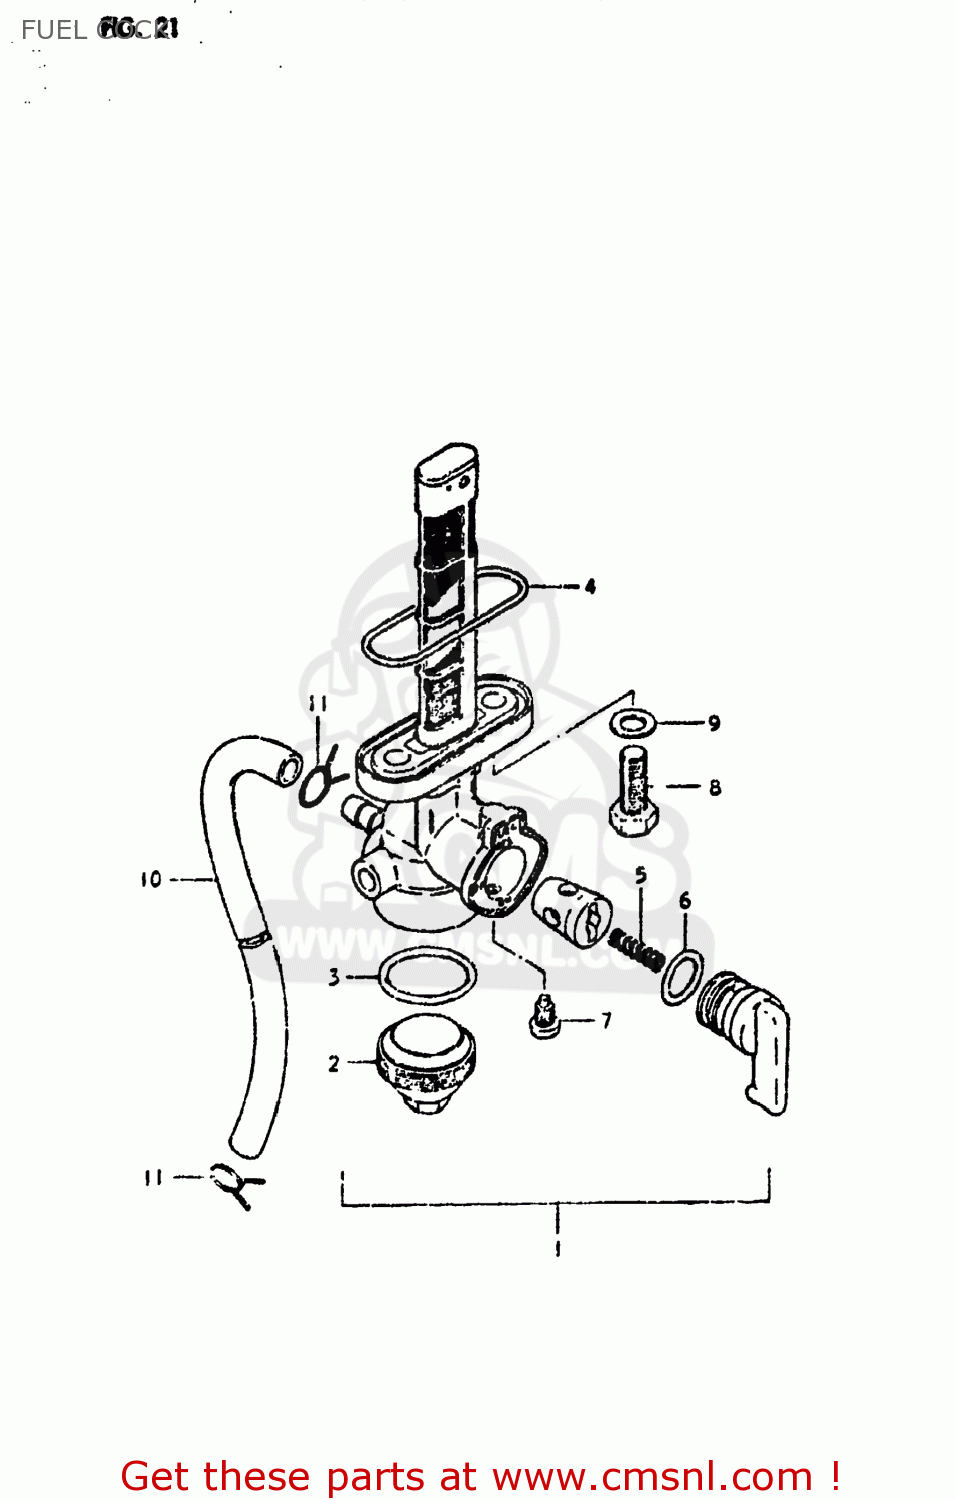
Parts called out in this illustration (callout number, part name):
1	COCK ASSEMBLY,FUEL
2	CUP,STRAINER
3	GASKET,FILTER (NAS)
4	O RING,FUEL COCK
5	SPRING
6	O-RING
7	SCREW
8	BOLT(6X20)
9	GASKET
10	HOSE
11	CLIP
